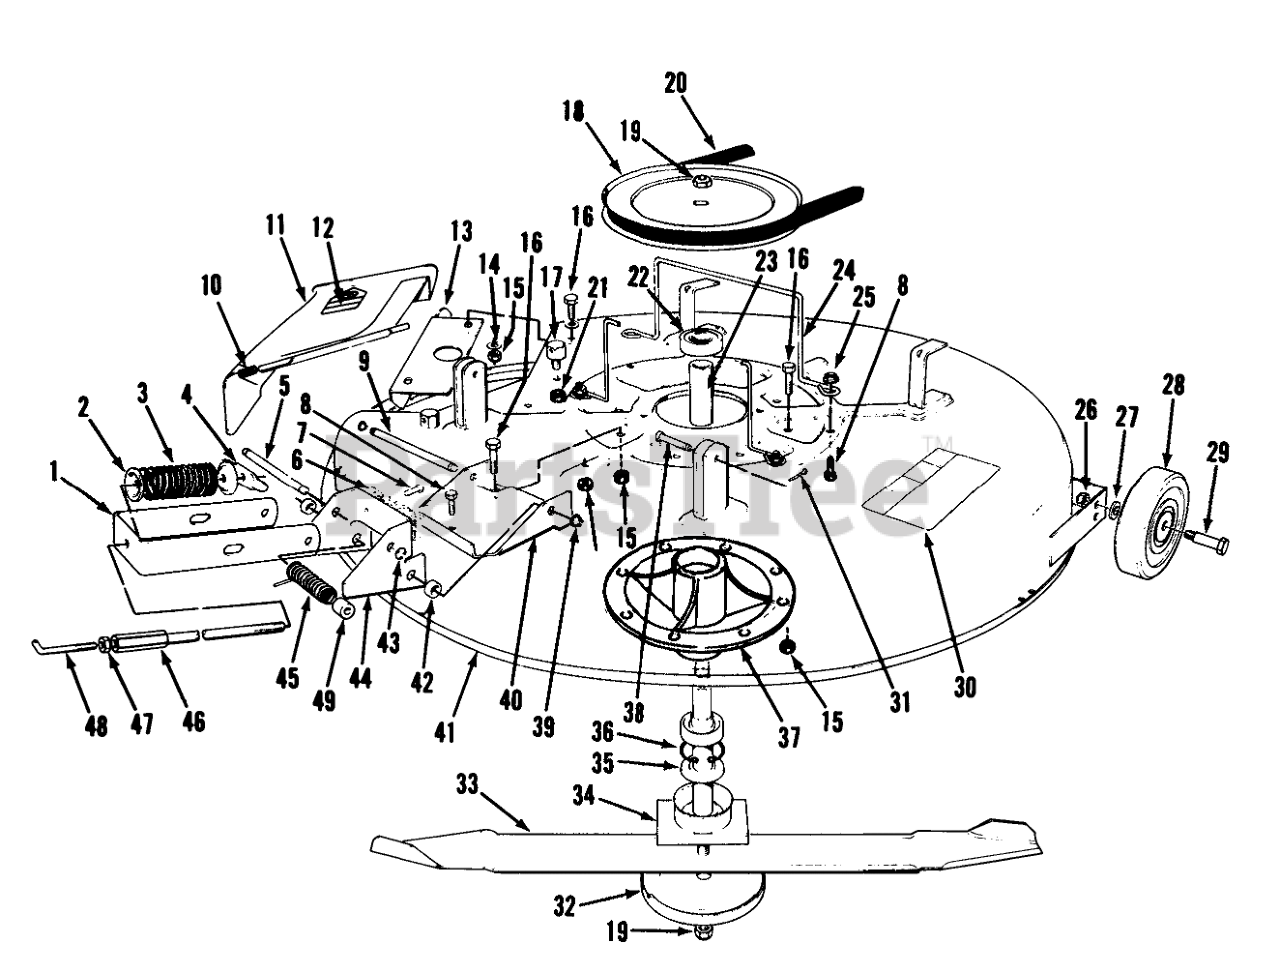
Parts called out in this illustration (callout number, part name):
1	Bracket-Engagement
2	RETAINER-SPR. TOP
3	SPRING-COMPRESSION
4	SHAFT-DECK ADJ.
5	Pin-Clevis
6	BRAKE PAD
7	RIVET .187 X 7/16 BRASS
8	SCREW-HH
9	CLEVIS PIN
10	SPRING
11	Deflector Assemby (Includes Reference #12)
12	DECAL-DANGER
13	Baffle Deck
14	WASHER-PLAIN
15	NUT-LOCK, NI
16	SCREW-HH
17	POST-PIVOT
18	PULLEY
20	V-BELT, DECK
21	NUT-LOCK, SIDE
22	BEARING-BALL
23	Spacer-Bearing
24	GUIDE-BELT
25	NUT-LOCK, HHF
26	NUT-LOCK, NI
27	WASHER-FLAT
28	WHEEL-DECK
29	BOLT-WHEEL
30	DECAL-DANGER, THROWN OBJECT
31	PIN-COTTER
32	Cup
33	Blade
34	SPINDLE SHAFT WA
35	SPACER-SPINDLE
36	RING-RETAINING
37	SPINDLE
38	PIN-CLEVIS
39	RING-RETAINING
40	DECK ENGAGE CHANNEL R
41	Cutter Deck
42	DECK BRAKE SPACER
43	E-RING
44	Support-Deck Brake Assembly (Includes Reference #6 & 7)
45	SPRING
46	ADJ HUB WA
47	NUT-JAM
48	ADJ. ROD
49	CHAIN TENSION ROLLER
